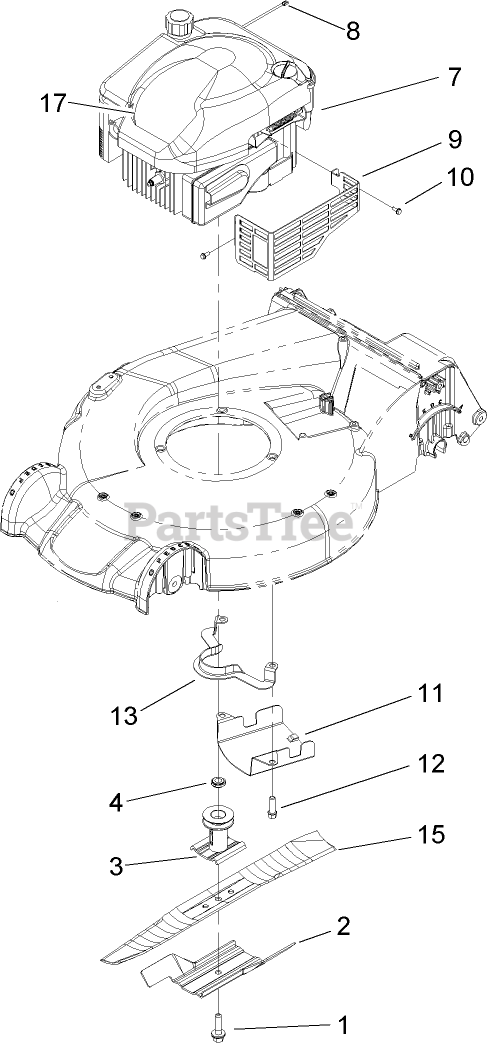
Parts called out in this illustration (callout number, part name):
2	ACCELERATOR-BLADE
3	DRIVER-BLADE
4	SPACER-DRIVER
7	Loose Parts Package
8	STOP-ROPE
9	SHIELD-MUFFLER
10	SCREW-TAPTITE
11	SHIELD-GRASS
12	SCREW-TAPTITE
13	GUIDE-BELT
17	DECAL-RECOIL
